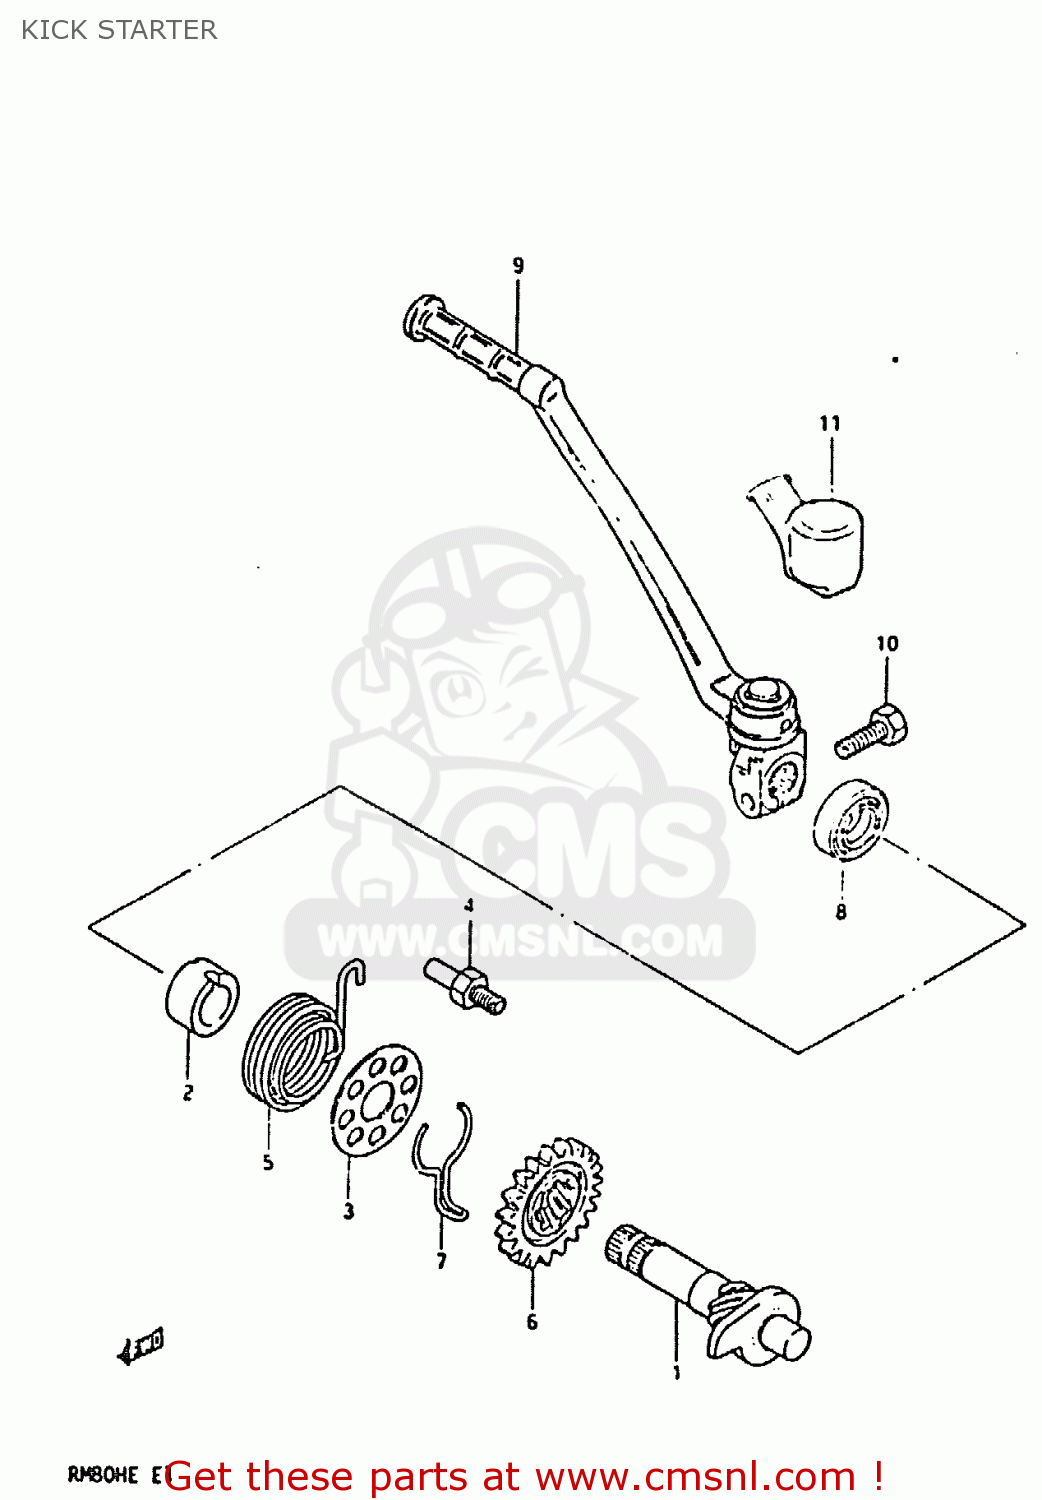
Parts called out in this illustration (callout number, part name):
1	SHAFT,KICK STARTER
2	GUIDE,KICK STARTER SFT SPRING
3	HOLDER,KICK STARTER SHAFT SPR
4	BOLT,KICK START SHAFT SPR HOOK
5	SPRING
6	GEAR,KICK STARTER DRIVE
7	SPRING,RETAINER
8	SEAL,OIL(14X24X6)
9	LEVER ASSEMBLY,KICK STARTER
10	BOLT
11	COVER,KICK LEVER JOINT
